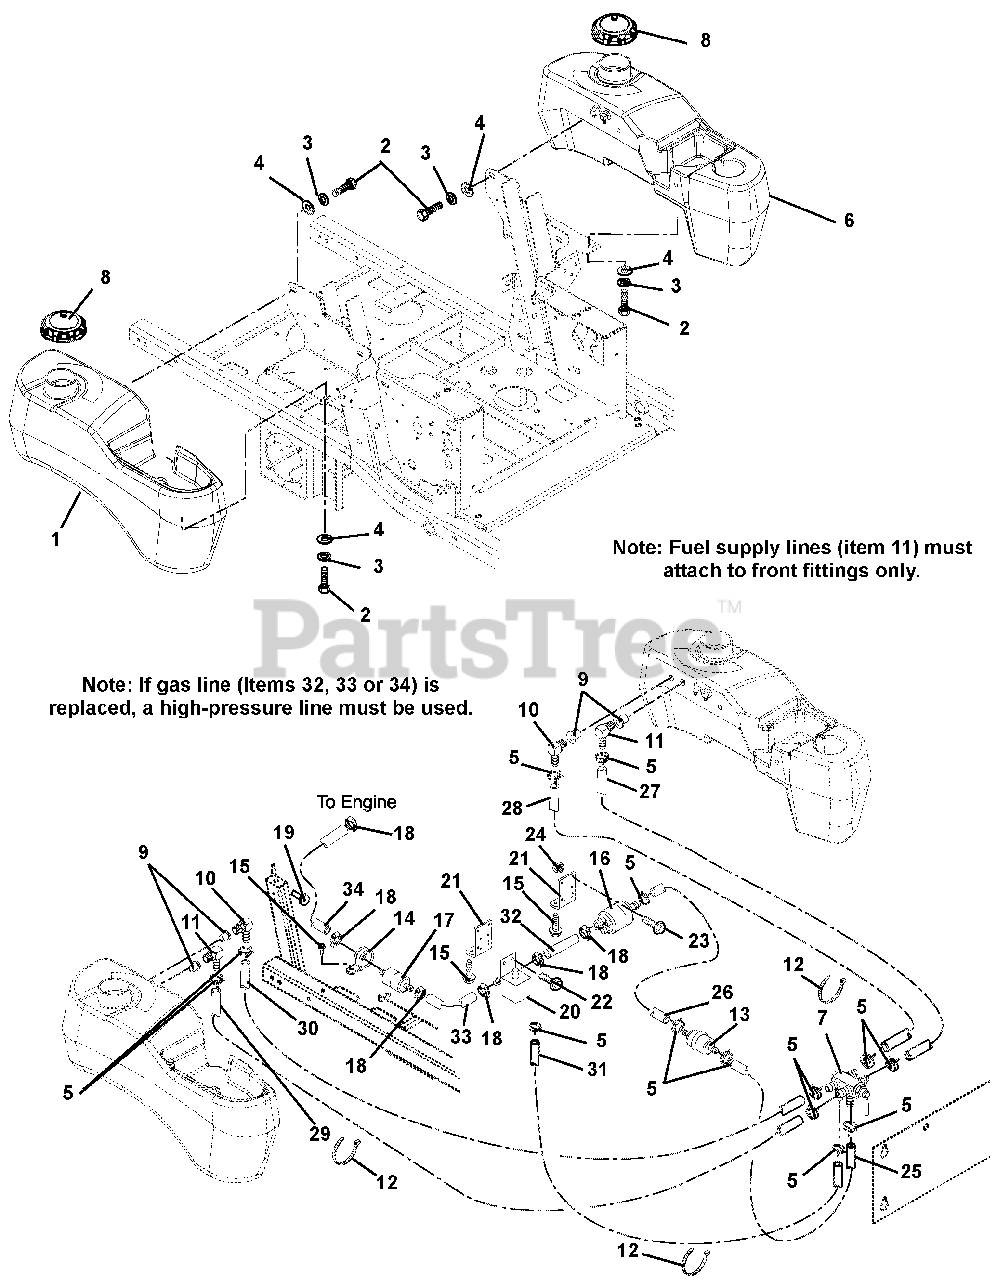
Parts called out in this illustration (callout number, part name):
1	Fuel Tank, Right Hand
2	Bolt, Hex .31-18 x .75 Grade 5
3	Washer, Locking .31 x .078
4	Washer, Flat Steel .38 x .875 x .083
5	Hose, Clamp
6	Tank, Left Hand Fuel (EYE-Q) 200 Series-EFI
7	Valve, Fuel
8	Cap, Gas
9	Bushing (Black in color. Does not replace or interchange with orange colored grommet.)
10	Fitting, Tank Elbow
11	Fitting, Tank Elbow
12	Tie, Cable
13	Filter, Fuel .31
14	Clamp, 2.18
15	Screw, Tapping .38-16 x .50 Hex Washer Head
16	Pump, EFI Fuel
17	Filter, Fuel
18	Hose Clamp
19	Tube Clip .75
20	Regulator, EFI Fuel
21	Bracket, Pump and Regular Mounting
22	Screw, Tapping .25-20 x .37 Hex Washer Head
23	Screw, Machine 10-24 x .50 Hex Washer Head
24	Nut, Locking Top 10-24
25	Hose, .31 ID Low Pressure
26	Hose, .31 ID Low Pressure
27	Hose, .31 ID Low Pressure Left Hand
28	Hose, .31 ID Low Pressure Left Hand
29	Hose, .31 ID Low Pressure Right Hand
30	Hose, .31 ID Low Pressure Right Hand
31	Hose, .31 ID Low Pressure
32	Gas Line .31 ID High Pressure
33	Gas Line .31 ID High Pressure
34	Gas Line .31 ID High Pressure
